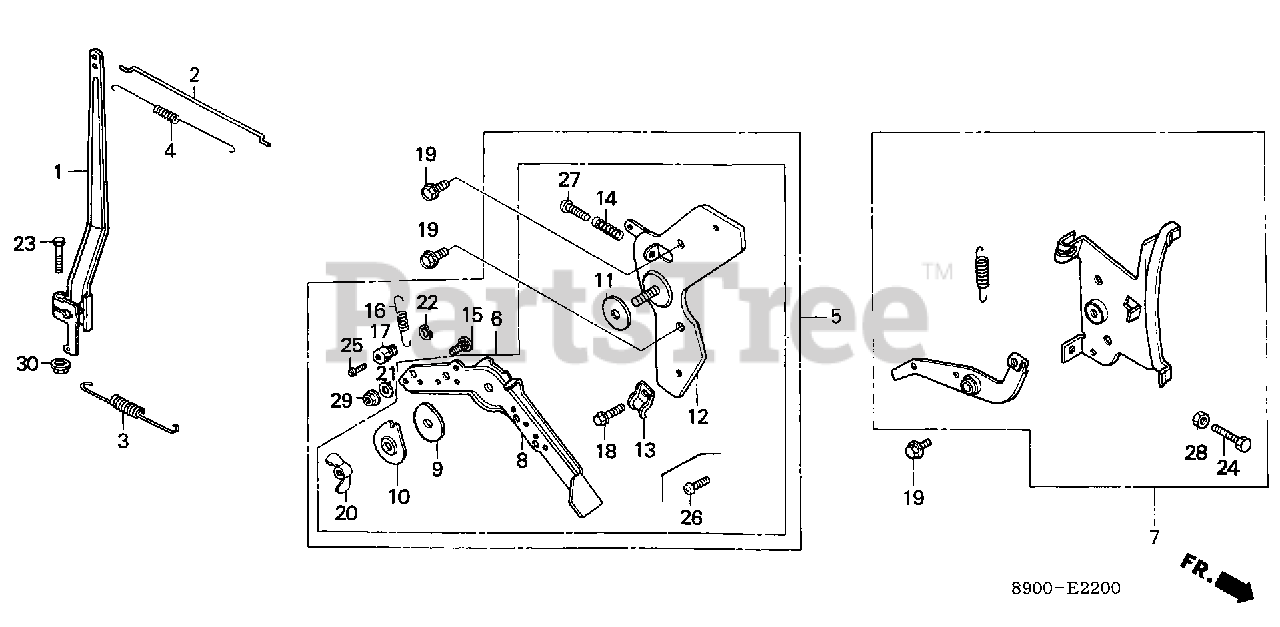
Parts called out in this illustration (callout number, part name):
1	ARM, GOVERNOR
2	ROD, GOVERNOR
3	SPRING, GOVERNOR (NOT AVAILABLE)
3	SPRING, GOVERNOR
4	SPRING, THROTTLE RETURN
4	SPRING, THROTTLE RETURN (NOT AVAILABLE)
6	CONTROL ASSY.
8	LEVER, CONTROL
9	SPRING, LEVER
10	WASHER, CONTROL LEVER
11	SPACER, CONTROL LEVER
12	BASE, CONTROL LEVER
13	HOLDER, CONTROL CABLE
14	SPRING, CONTROL ADJUSTING
19	BOLT, FLANGE (6X12) (CT200)
20	WINGNUT (6MM)
23	BOLT, HEX. (6X25)
26	SCREW, PAN (5X10)
27	SCREW, PAN (5X22)
30	NUT, FLANGE (6MM)
